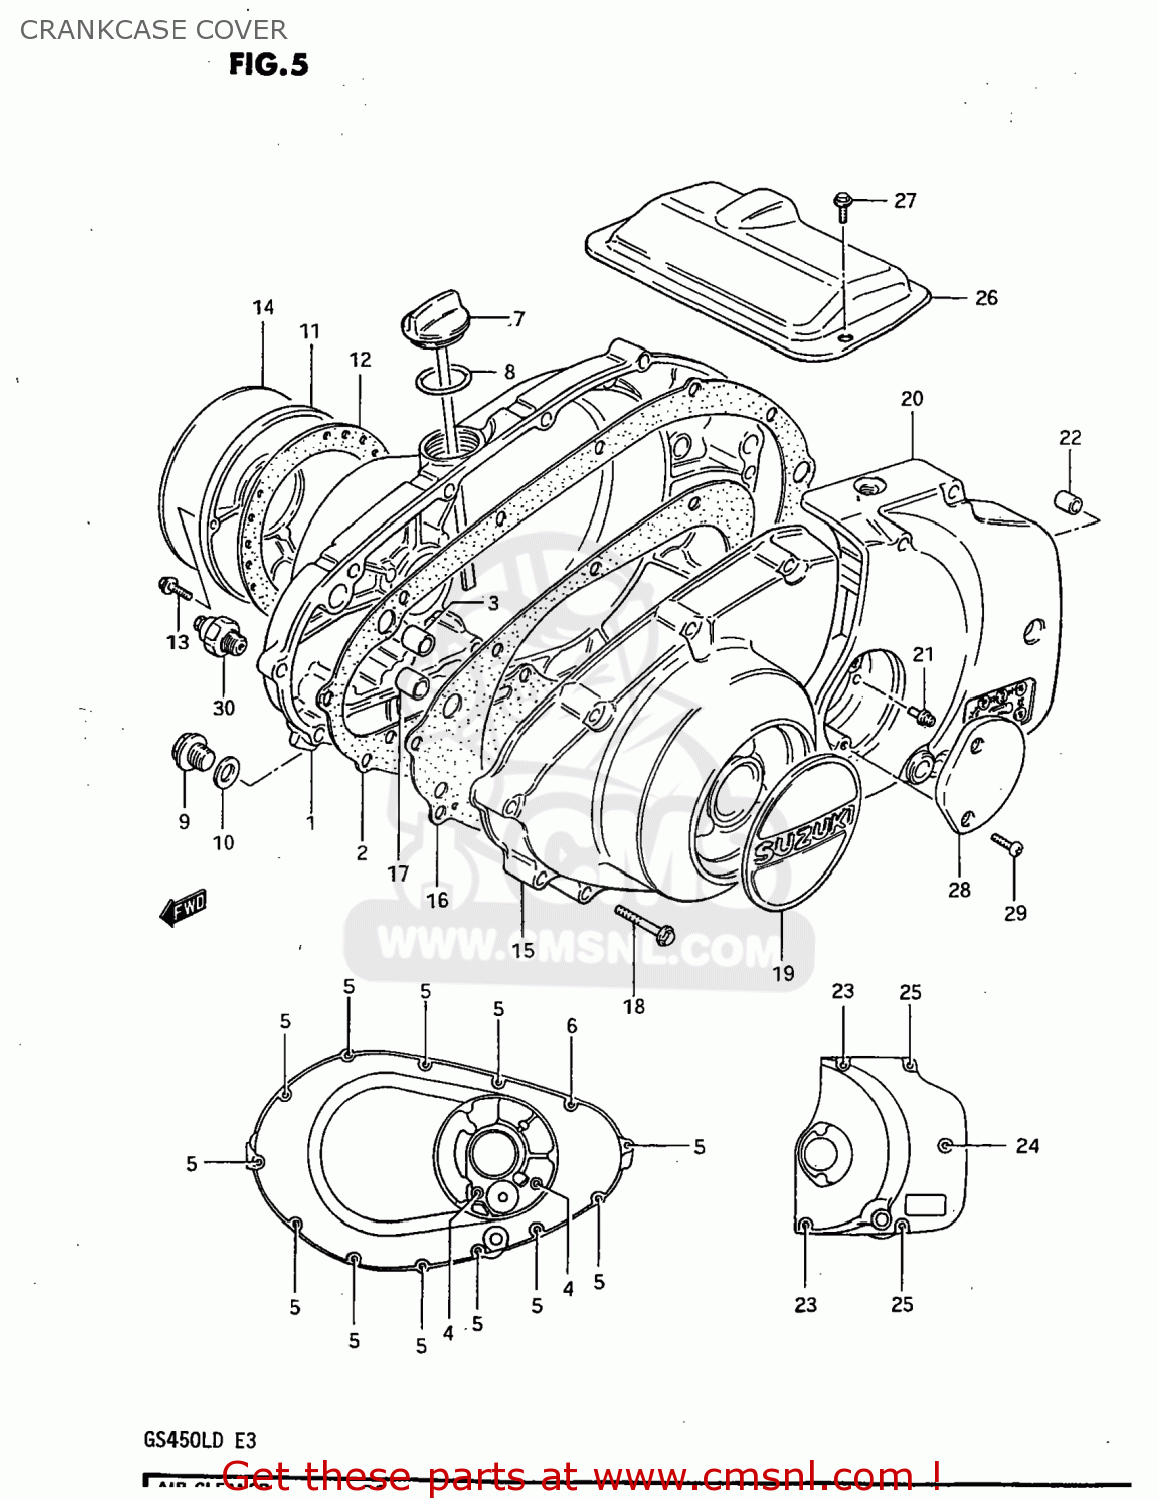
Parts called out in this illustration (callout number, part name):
1	COVER,CLUTCH
2	GASKET,CLUTCH COVER (MCA)
3	PIN
4	BOLT (6X55)
5	BOLT (6X35)
6	BOLT
7	GAUGE,OIL LEVEL
8	O-RING
9	PLUG (14X12)
10	GASKET(14X19.2X2) (NAS)
11	COVER,CONTACT BREAKER
12	GASKET,CONTACT BREAKER COVER (NAS)
13	BOLT 5X16
14	EMBLEM,MAGNETO COVER
15	COVER,MAGNETO
16	GASKET,MAGNETO COVER (MCA)
17	PIN
18	BOLT (6X35)
19	EMBLEM,MAGNETO COVER
20	COVER,ENGINE SPROCKET
21	NIPPLE
22	PIN
23	BOLT (6X65)
24	BOLT (6X50)
25	BOLT (6X40)
26	COVER,STARTER MOTOR
27	BOLT
28	CAP,CLUTCH RELEASE ADJUST
29	SCREW 5X12
30	SWITCH ASSEMBLY
